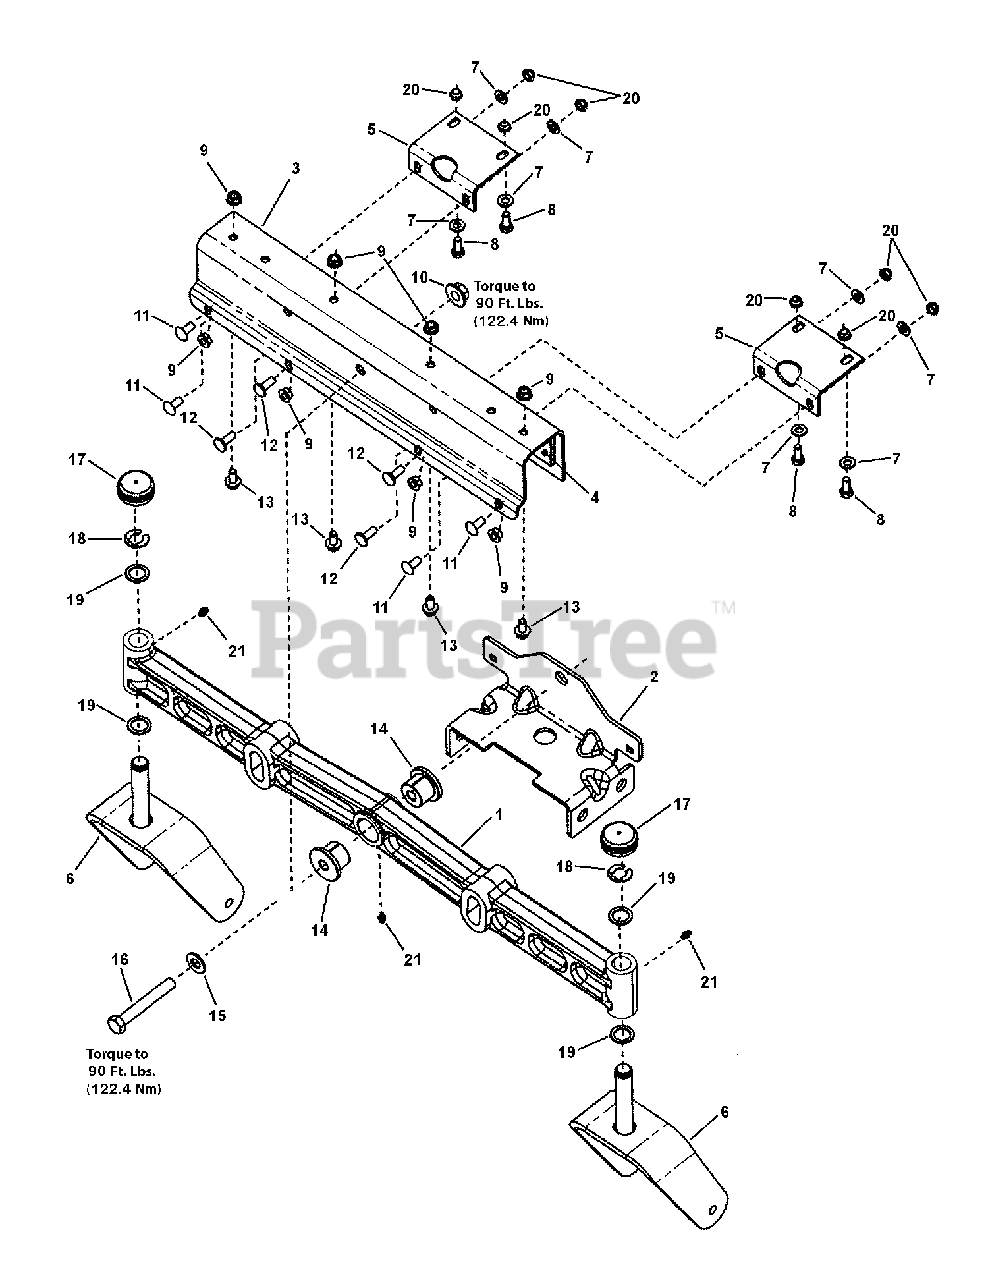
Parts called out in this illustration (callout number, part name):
1	AXLE, Front Iron Casting Machined ZT 2007
2	BRACKET, Hanger, Front (46/52)
3	BRACKET, Axle
4	PLATE, Friction, Adhesive Backed
5	BRACKET, Axle Support
6	WELDMENT, Caster Yoke & Spindle, Black
7	WASHER, 5/16" Flat
8	SCREW, 5/16-18 x 3/4" Hex Head Cap, GR 5, YZ
9	NUT, 5/16-18 Flange Lock, YZ
10	NUT, 1/2-13 Hex Flange Two-Way Lock Black
11	BOLT, 5/16-18 x 3/4" Round Head Short Square Neck, GR 5, YZ
12	BOLT, 5/16-18 x 7/8" Round Head Short Square Neck, GR 5, Black
13	BOLT, 5/16-18 x 5/8" Hex Flange lock, GR 5, YZ
14	BUSHING, Axle Pivot
15	WASHER, 1/2" Flat (SAE)
16	SCREW, 1/2-13 x 3-1/2" Hex Head Cap, YZ
17	HUB CAP, 1.481 I.D x .62 Long Red Poly
18	RING, Klipring External for .750 Dia. Shaft Bln
19	WASHER, 0.750 ID x 1.60 OD x .05 Thick, Black
20	NUT, 5/16-18 Hex Top Lock, GR B
21	LUBE FITTING, 3/16" Press Fit
